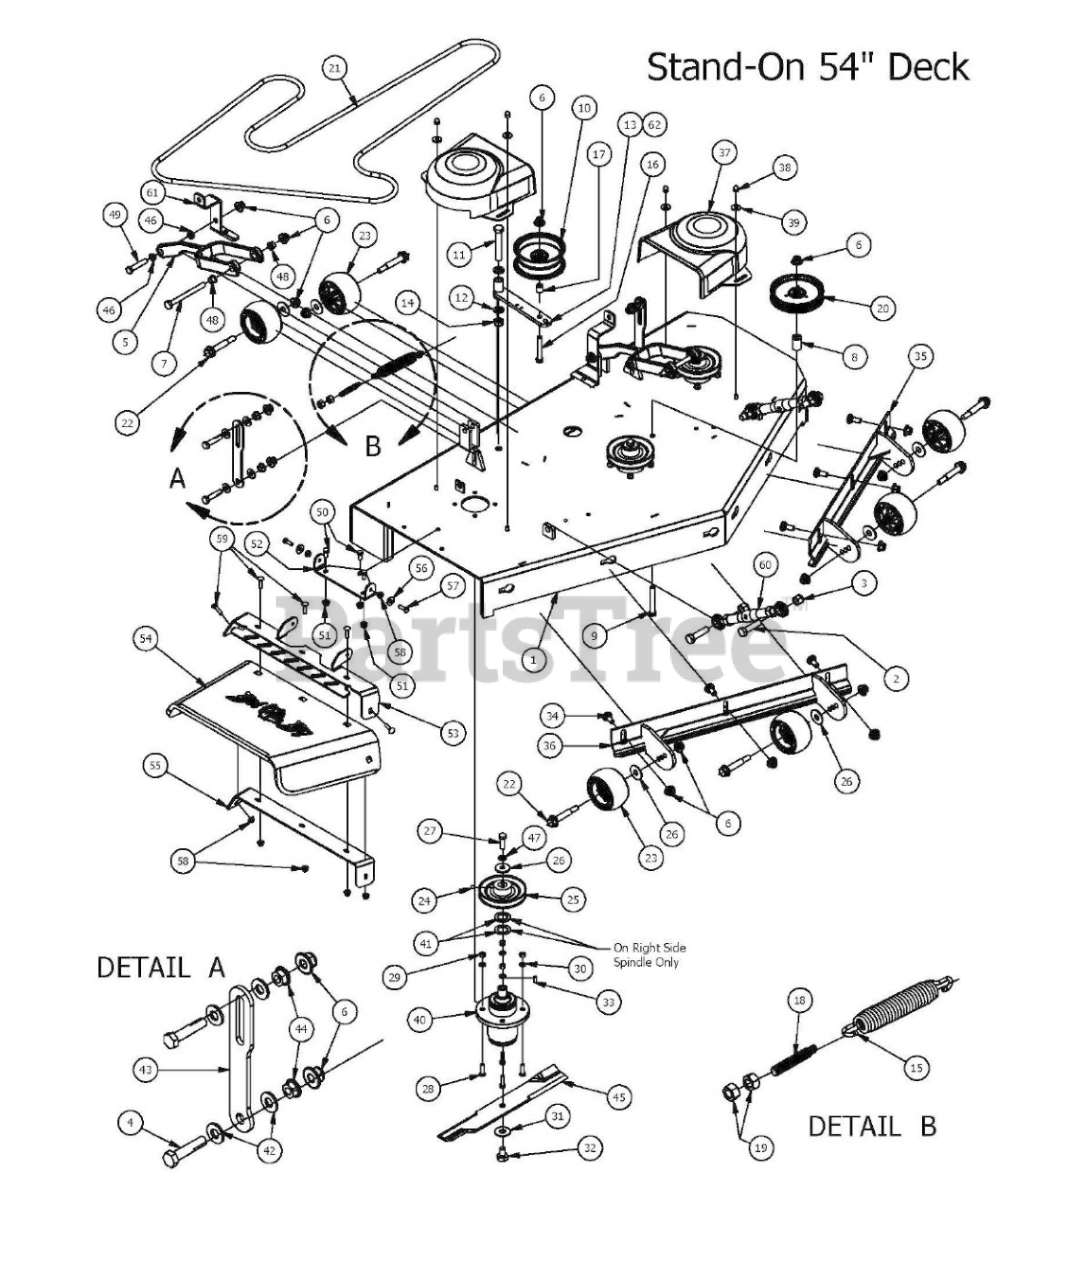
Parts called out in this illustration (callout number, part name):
1	54" 2015 Stand-On Deck (Welded Assembly)
2	5/8" x 2 1/2" Hex Bolt
3	5/8 Std NC Nylock Nut
4	1/2-13X 2-1/4 GR Hex Bolts
5	Deck Arm Assembly
6	1/2-13 Nylon Flange Nut
7	1/2" x 5 1/2" Bolt
8	Idler Pulley Standoff
9	1/2 x 3 1/2 Flange Bolt Grade 8
10	5 3/4" Deck Idler Pulley
11	5/8" x 4" Hex Bolt
12	.630 ID Plastic Washer
13	Deck Idler
14	5/8" Nylock (1/2 Jam)
15	2009 Deck/Pump Idler Spring
16	1/2-13 x GR 5 Hex Bolt Zinc
17	Spacer 3/4 OD x 1/2 ID x 3/4 Length
18	All Thread-Pump Idler Tensioner
19	1/2" Hex Nut
20	5-3/4 Idler Pulley-Capitol Stampings
21	42" Deck Belt B120
22	Deck Wheel Bolt
23	Anti-Scalp Rollers
24	5/16 Set Screw
25	5.25" Deck Spindle Pulley
26	1/2" Belleville Washer
27	1/2"-20 x 1 1/2 Grade 5 Fine Thread Bolt
28	3/8" x 1 1/4" Hex Bolt
29	3/8-16 Hex Nuts Zinc
30	3/8" Lock Washer
31	5/8" Flat Washer
32	5/8" x 1 1/2" Grade 8 Hex Bolt (Fine)
33	1/4" x 1" Key
34	1/2" x 1 1/4 Carriage Bolt
35	54 Deck Adustable Front (Left)
36	54 Deck Adustable Front (Right)
37	Pulley Cover
38	Acorn nut-pulley Cover
39	.360 ID Plastic Washer-Black
40	OUTLAW SPINDLE ASSEMBLY
41	11/8" Flat Spacer
42	.505 Nylon Spacer
43	Longer deck hanger
44	1/2" Flange Nut
45	54" Deck Fusion Blade For Outlaw
46	Flange Bushing For Lower Deck Arm
47	1/2" Lock Washer
48	Flange Bushing For Upper Deck Arm
49	1/2" x 3" Hex Bolt
50	3/8" x 3/4" Hex Bolt
51	3/8" Flange Nut
52	Discharge Chute Hanger (deck mounted)
53	60" Discharge Chute Upper Hanger
54	Rubber Discharge Chute
55	60" Discharge Lower Bracket
56	.360 ID Plastic Washer
57	5/16" x 1" Bolt
58	5/16" Nylock Flange Nut Zinc
59	5/16" x 1 1/4" Carriage Bolt
60	Turnbuckle
61	Stand-On Deck Stop
62	Deck Idler Arm Assembly
